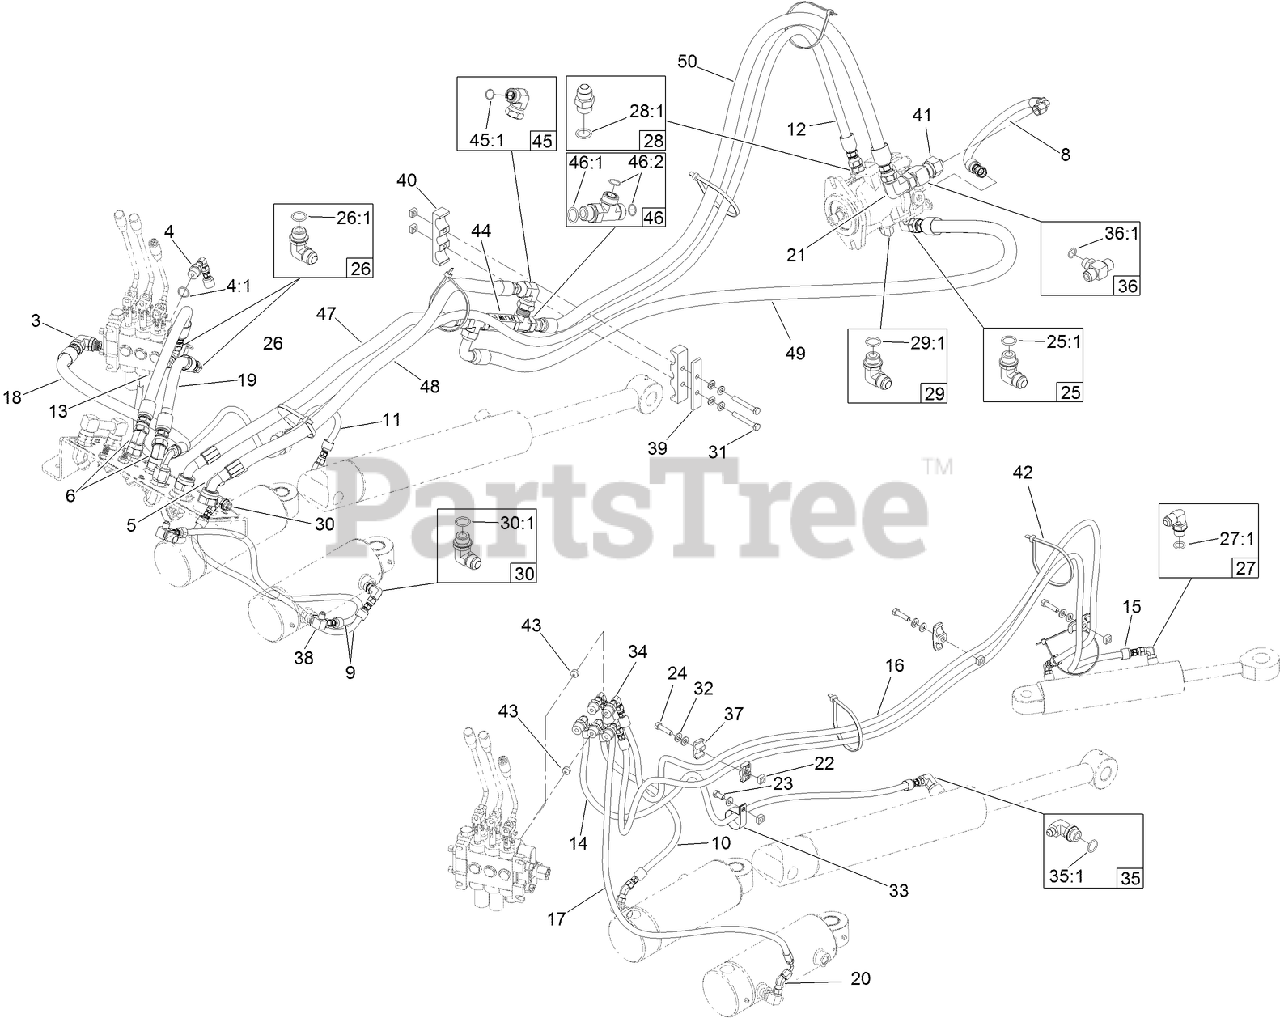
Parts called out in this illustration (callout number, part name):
3	FITTING-ELBOW, 90 DEG
4	ADAPTER-HYD
4:1	O-RING
5	FITTING-ELBOW, 45 DEG
6	FITTING-ELBOW, 45 DEG
8	HYD HOSE ASM
9	HYD HOSE ASM
10	HYD HOSE ASM
11	HYD HOSE ASM
12	HYD HOSE ASM
13	HYD HOSE ASM
14	HYD HOSE ASM
15	HYD HOSE ASM
16	HYD HOSE ASM
17	HYD HOSE ASM
18	HYD HOSE ASM
19	HYD HOSE ASM
20	FITTING-ELBOW, 45 DEG
21	ELBOW-SWIVEL, 90 DEG
22	NUT-SQUARE
23	SCREW-HH
24	SCREW-HH
25	FITTING-ELBOW, 90 DEG
25:1	O-RING
26	FITTING-ELBOW, 90 DEG
26:1	O-RING
27	FITTING-ELBOW, 90 DEG
27:1	O-RING
28	FITTING-STRAIGHT
28:1	O-RING
29	FITTING-90 DEG
29:1	O-RING
30	FITTING-ELBOW, 90 DEG
30:1	O-RING
31	BOLT-HH
32	WASHER-FLAT
33	CLAMP-R
34	ELBOW-SWIVEL, 90 DEG
35	FITTING-ELBOW, 90 DEG
35:1	O-RING
36	FITTING-TEE
36:1	O-RING
37	CLAMP-TUBE
38	TEE-SPECIAL
40	BLOCK-CLAMP (HOSE-HYD)
41	FITTING-Restrictor
42	TIE-CABLE
43	ORIFICE
44	VALVE-CHECK
45	FITTING-ELBOW 90
45:1	O-RING
46	FITTING-TEE
46:1	O-RING
46:2	O-RING
47	HYD HOSE ASM
48	HYD HOSE ASM
49	HYD HOSE ASM
50	HYD HOSE ASM
